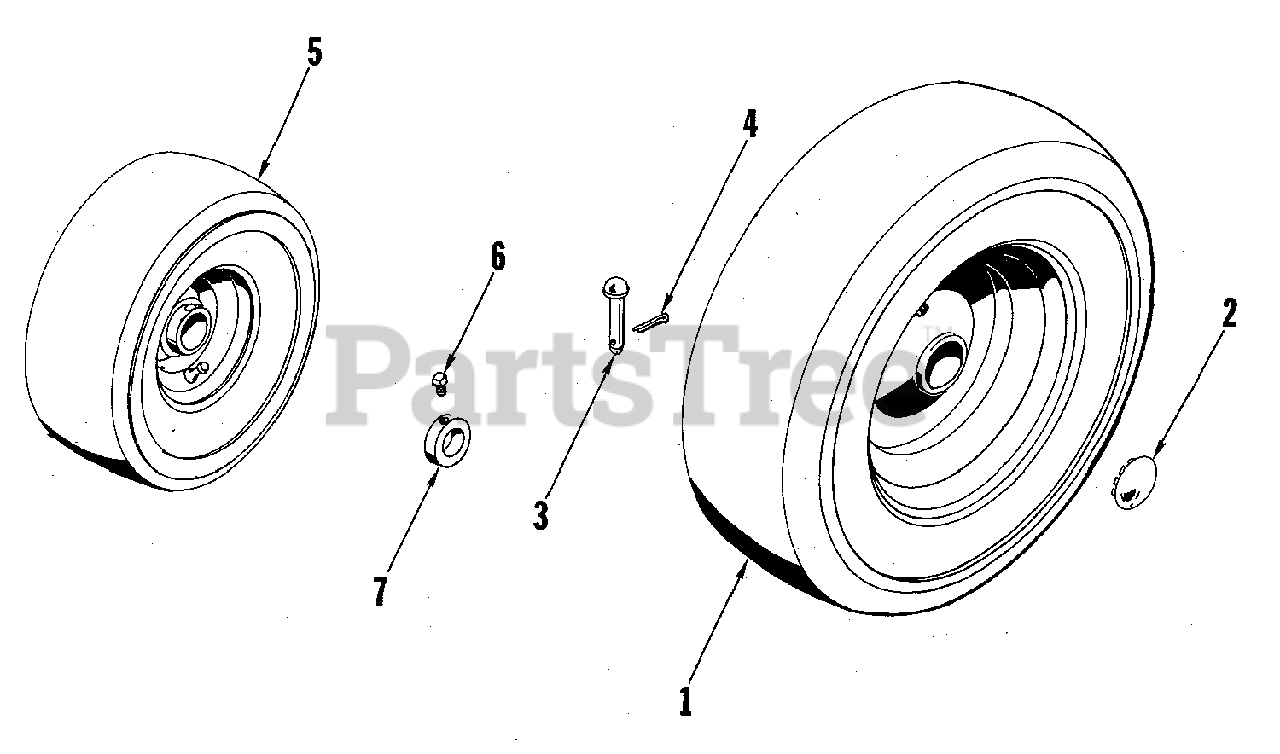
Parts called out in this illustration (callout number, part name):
1	REAR WHEEL & TIRE ASSEMBLY
2	BUTTON, Plug
4	PIN, Cotter, 1/8 x 3/4
5	FRONT WHEEL & TIRE ASSEMBLY
6	SCREW, Set, 5/16-18 x 5/16
